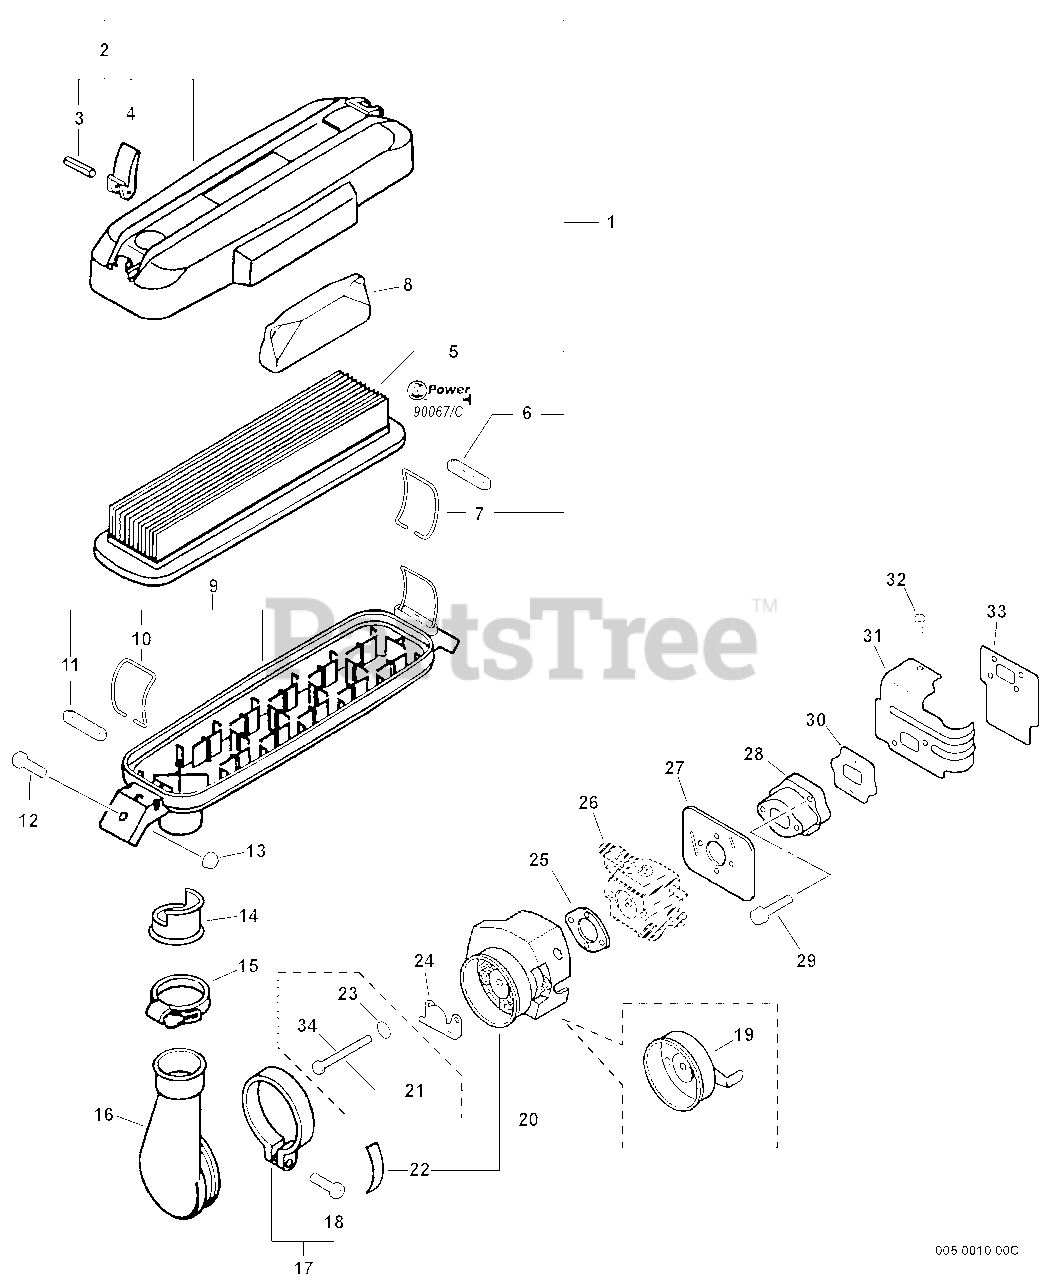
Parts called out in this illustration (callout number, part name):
1	AIR FILTER KIT
2	AIR FILTER COVER ASSY
3	PIN - SPRING -- 3X25
5	FILTER, AIR
6	RETAINER
7	RING, RETAINING
8	SILENCER
9	AIR FILTER CASE ASSY
10	RING, RETAINING
11	RETAINER
12	SCREW - 5X14
13	NUT - 5 -- FLANGE
15	CLAMP, HOSE
16	ADAPTOR, INTAKE
17	CLAMP KIT
18	SCREW - 5X25
19	BRACKET, AIR CLEANER - METAL
20	BRACKET KIT - PLASTIC
21	SCREW - 5X57
22	LABEL - CHOKE
23	WASHER - 6
24	PLATE, PREVENT
25	GASKET, INTAKE
26	CARBURETOR
27	GASKET, INTAKE
28	INSULATOR, INTAKE
29	SCREW - 5X25
30	GASKET, INTAKE
31	COVER, CYLINDER - EXHAUST
32	SCREW - 5X10
33	SHIELD, INTAKE
34	SCREW - 5X55
35	RePower TUNE-UP KIT
